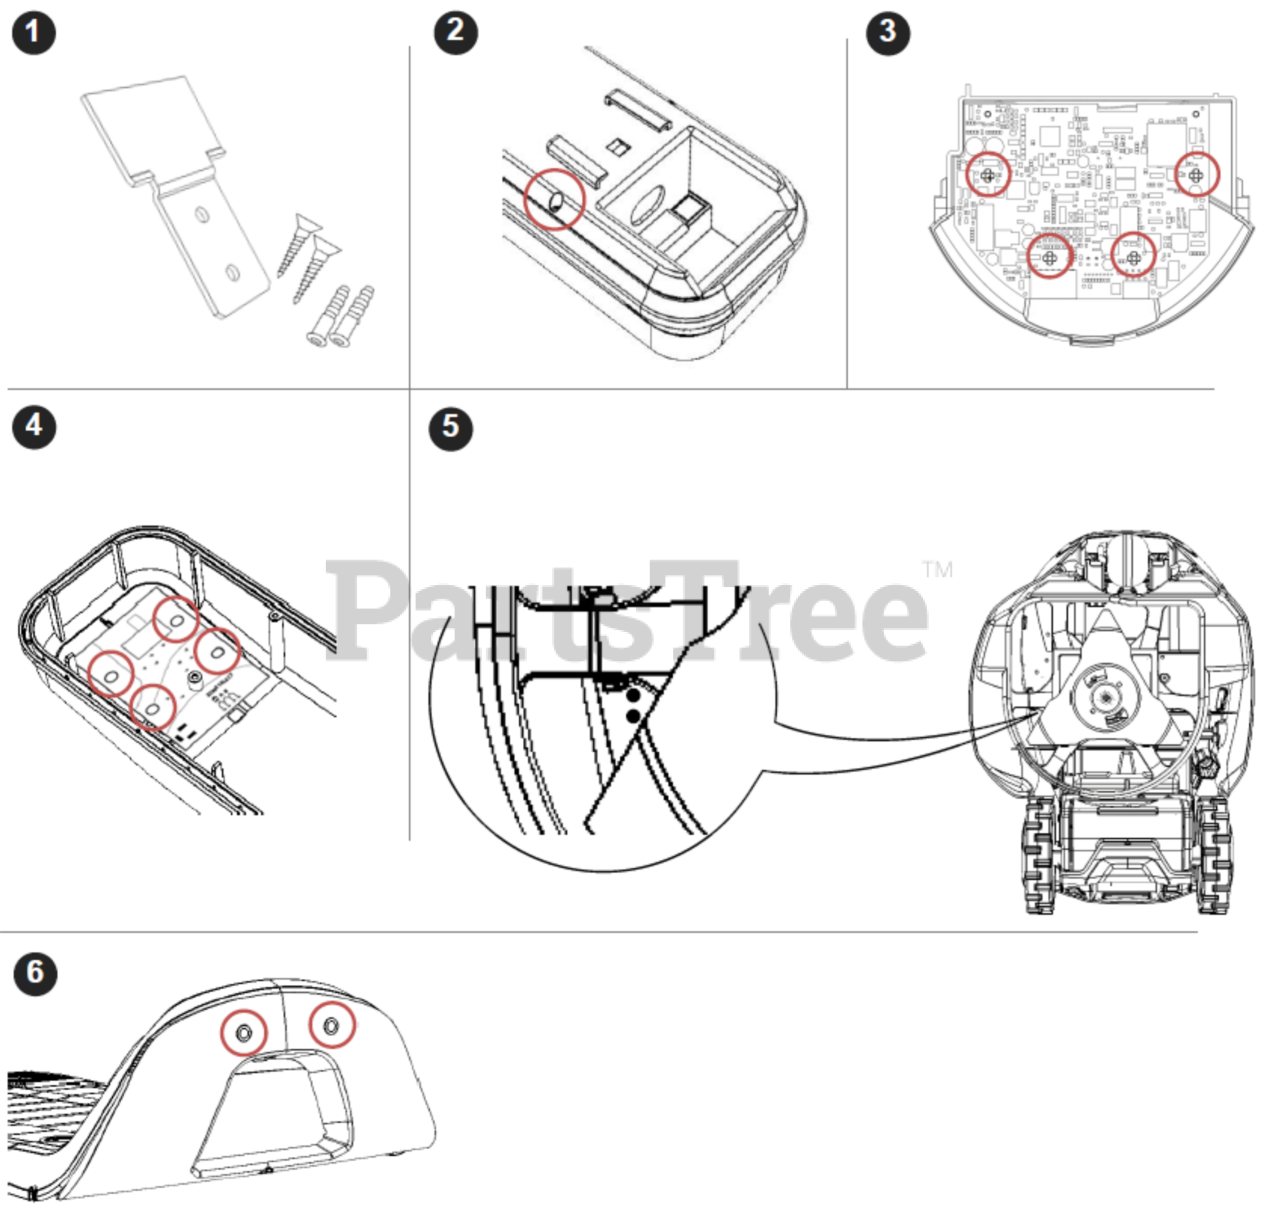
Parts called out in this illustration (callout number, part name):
3	EJOT PT WN1451 K50x12 Torx
5	M6 SCREW DIN 16 912 12.9
6	M4X10 PHILLIPS HEAD SCREW
